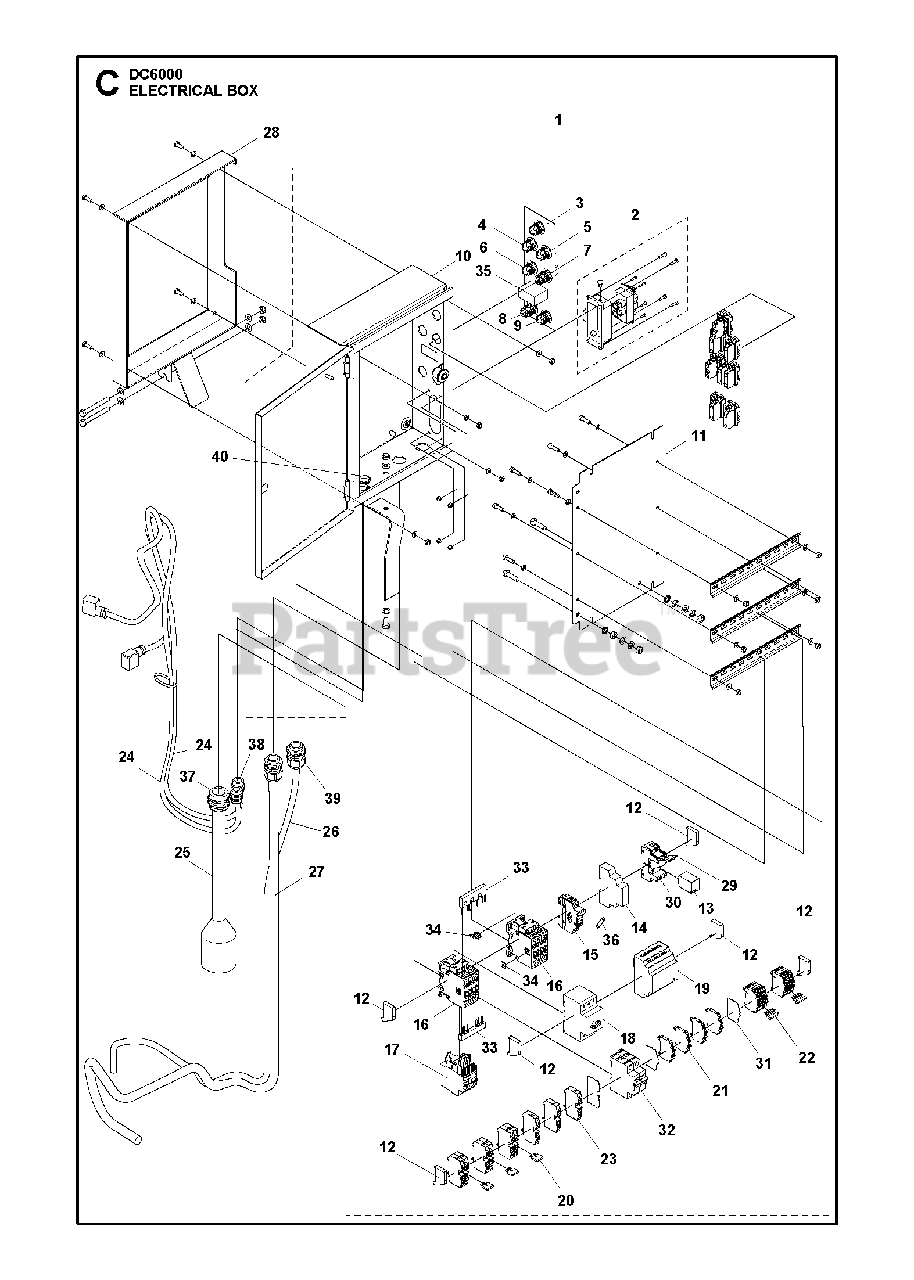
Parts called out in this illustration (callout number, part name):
11	PLATE-01 EU/AUS / -02 UL/CSA
24	CABLE ASSY-01 EU / -02 AUS / -03 UL/CSA
25	CABLE ASSY-01 EU/AUS / -02 UL/CSA
26	CABLE ASSY-01 EU/AUS / -02 UL/CSA
